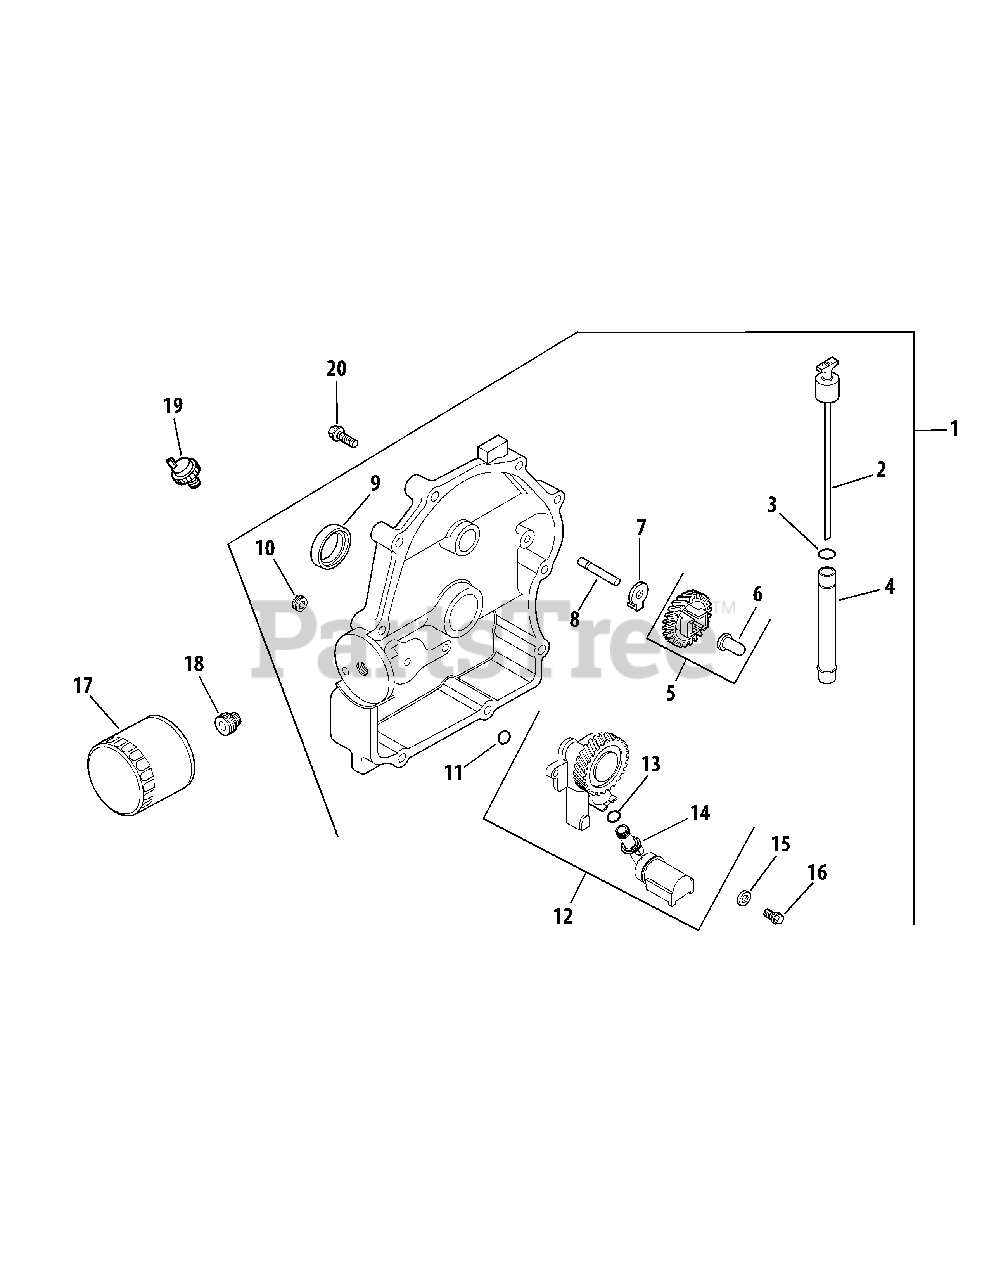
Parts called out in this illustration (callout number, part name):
1	Plate Assy, Closure (Incl. Ref #2-15)
4	Tube, Oil Fill/Dipstick
5	Kit, Governor Gear (Incl. Ref #6)
6	Pin, Governor Regulating
8	Shaft, Governor Gear
9	Seal, Oil (PTO end)
10	Plug, Pipe 1/8
12	Oil Pump Assy (Incl. Ref #13-14)
13	O-Ring, Oil Pick-up
14	Pick-up, Oil
15	Washer, Plain
16	Screw, Hex Flange, M6 x 1.0 x 25
18	Nipple, Oil Filter
19	Switch, Pressure
20	Screw, Hex Flange, M8 x 1.25 x 45
